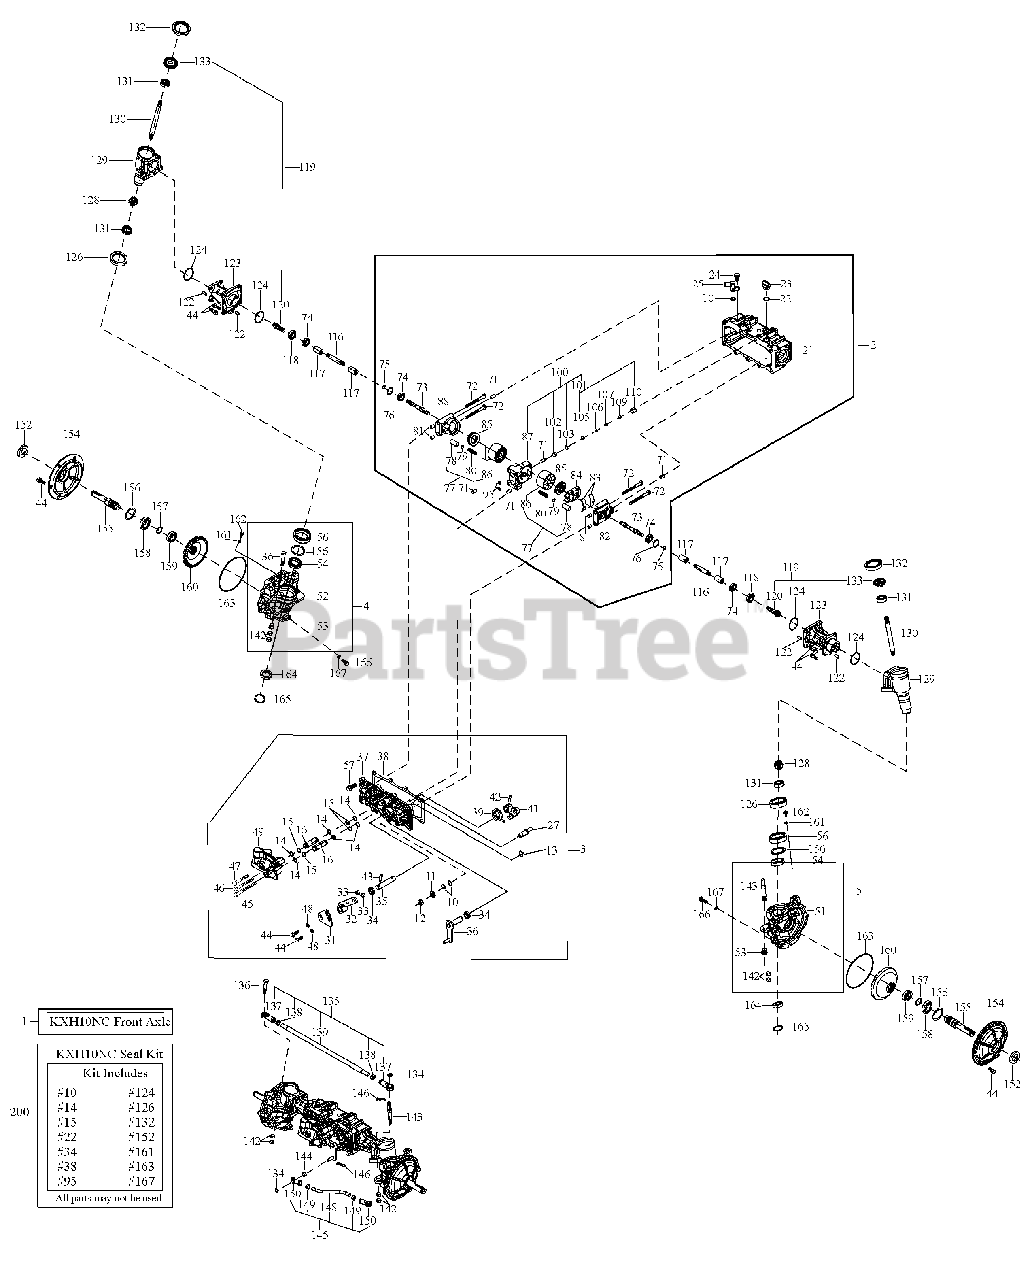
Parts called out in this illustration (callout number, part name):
1	FRONT AXLE, Tuff Torq KXH10NC
3	*MOTOR COVER, Complete
4	*FRONT GEAR BOX, Left, Complate
5	*FRONT GEAR BOX, Right, Complete
10	O-RING 1A P14
15	BACK-UP RING
16	*JOINT PIPE
21	*FRONT AXLE CASE
24	BOLT 8 x 20
27	*FULCRUM
31	*ADJUST PLATE
32	*CONTROL LEVER
35	*CONTROL SHAFT
36	*CAM LEVER
37	*MOTOR COVER
38	GASKET COVER
39	*RETURN SPRING
41	*CONTROL ARM
42	SPRING PIN 6 x 25
44	BOLT 8 x 25
49	*CONNECTING BLOCK
72	BOLT 8 x 90
77	CYLINDER BLOCK KIT
82	*SWASH SUPPORT, Right
83	THRUST METAL
84	*SWASH PLATE
85	THRUST BEARING 51106
88	*SWASH SUPPORT, Left
100	*CENTER CASE 10CC, Complete
101	*CHECK VALVE, Complete
102	*COLLAR
116	*JOINT SHAFT N
117	*SPLINE COLLAR B
119	*KIT, Bevel Gear
123	*AXLE FLANGE
124	PACKING G 45.0
129	*FRONT GEAR CASE
132	SEAL CAP 56
135	TIE ROD, Complete
136	*TIE ROD PIN, Left
143	*TIE ROD PIN, Right
145	STEERING ROD COMPLETE N
152	SEAL TC254708
154	*FRONT BEARING COVER
155	*FRONT AXLE SHAFT
158	BEARING 6005 C3
163	PACKING G140.0
164	COLLAR 30*38*4
167	SEAL WASHER 8
200	*SEAL KIT
